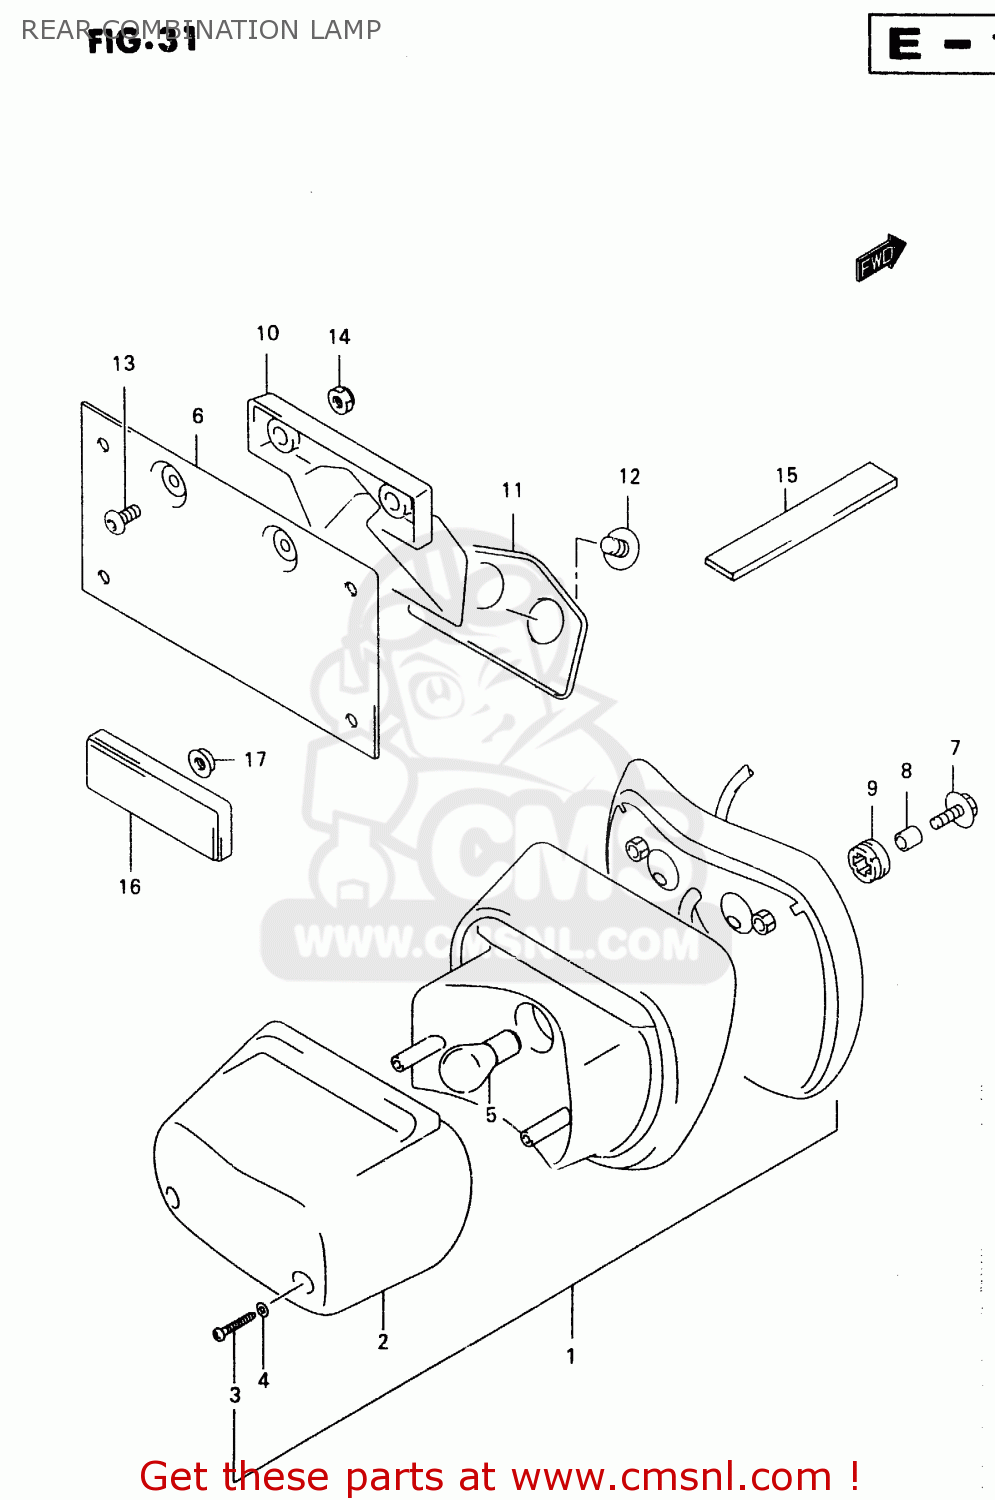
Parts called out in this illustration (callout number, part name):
1	LAMP ASSY,RR COMBINATION
2	LENS
3	SCREW
4	GASKET (NAS)
5	BULB(12V21/5W)
6	HOLDER,LICENSE
7	BOLT 6X20
8	SPACER(6.5X10X10)
9	CUSHION
10	STAY,LICENSE PLATE HOLDER
11	CUSHION,LICENSE PLATE HOLDER
12	BOLT(6X16)
13	SCREW(6X16)
14	NUT
15	PROTECTOR(20X90)X1.0
16	REFLECTOR ASSEMBLY,REAR
17	NUT
